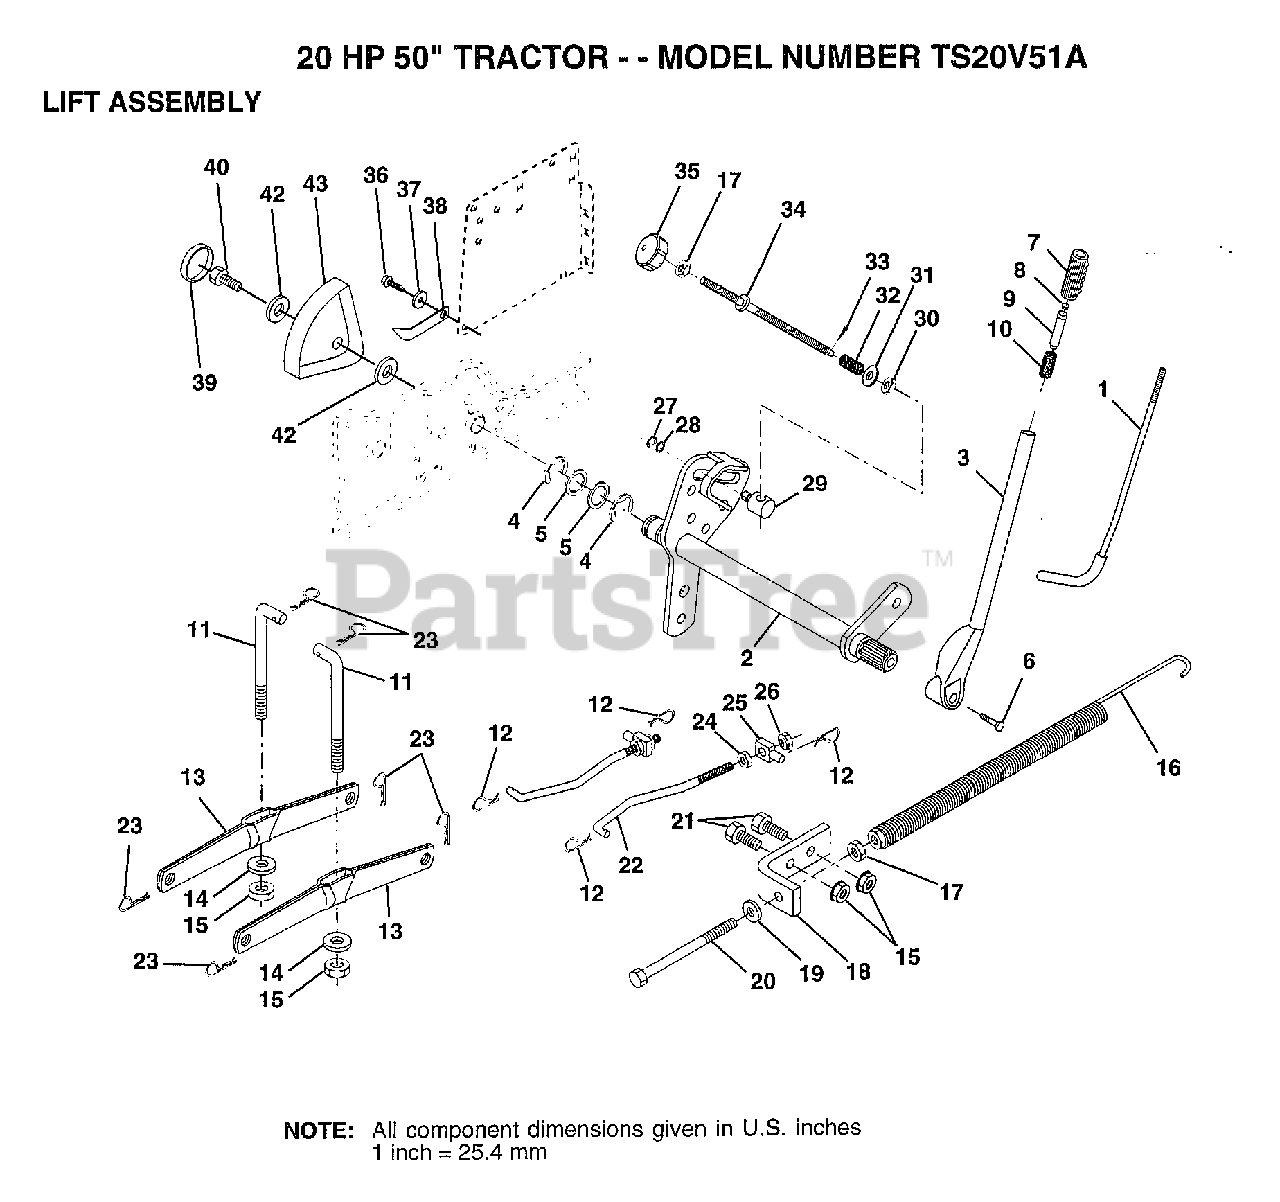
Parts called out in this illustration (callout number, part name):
1	LEVER ROD LT
4	E-RING
5	WASHER
6	"BOLT,HEX"
7	GRIP HANDLE
10	SPRING T
12	RETAINER.SPRING
14	BEARING PVT LH
15	NUT
17	NUT
18	BRACKET SPRING AS
19	WASHER
20	BOLT-ADJ SPRING T
21	BOLT
22	LINK.FRONT
24	NUT
25	TRUNION
26	NUT.LK.W/WSH.1/2.
27	KLIP RING
28	WASHER
29	TRUNION LT
30	NUT T
31	WASHER
32	SPRING.COMP.INF.H
34	ROD.ADJ.LIFT
35	KNOB INF 3/8-16
36	SCREW
37	WASHER T
38	POINTER HGT IND
39	"PLUG,HOLE"
40	SCREW
42	WASHER
43	HEIGHT INDICATOR
